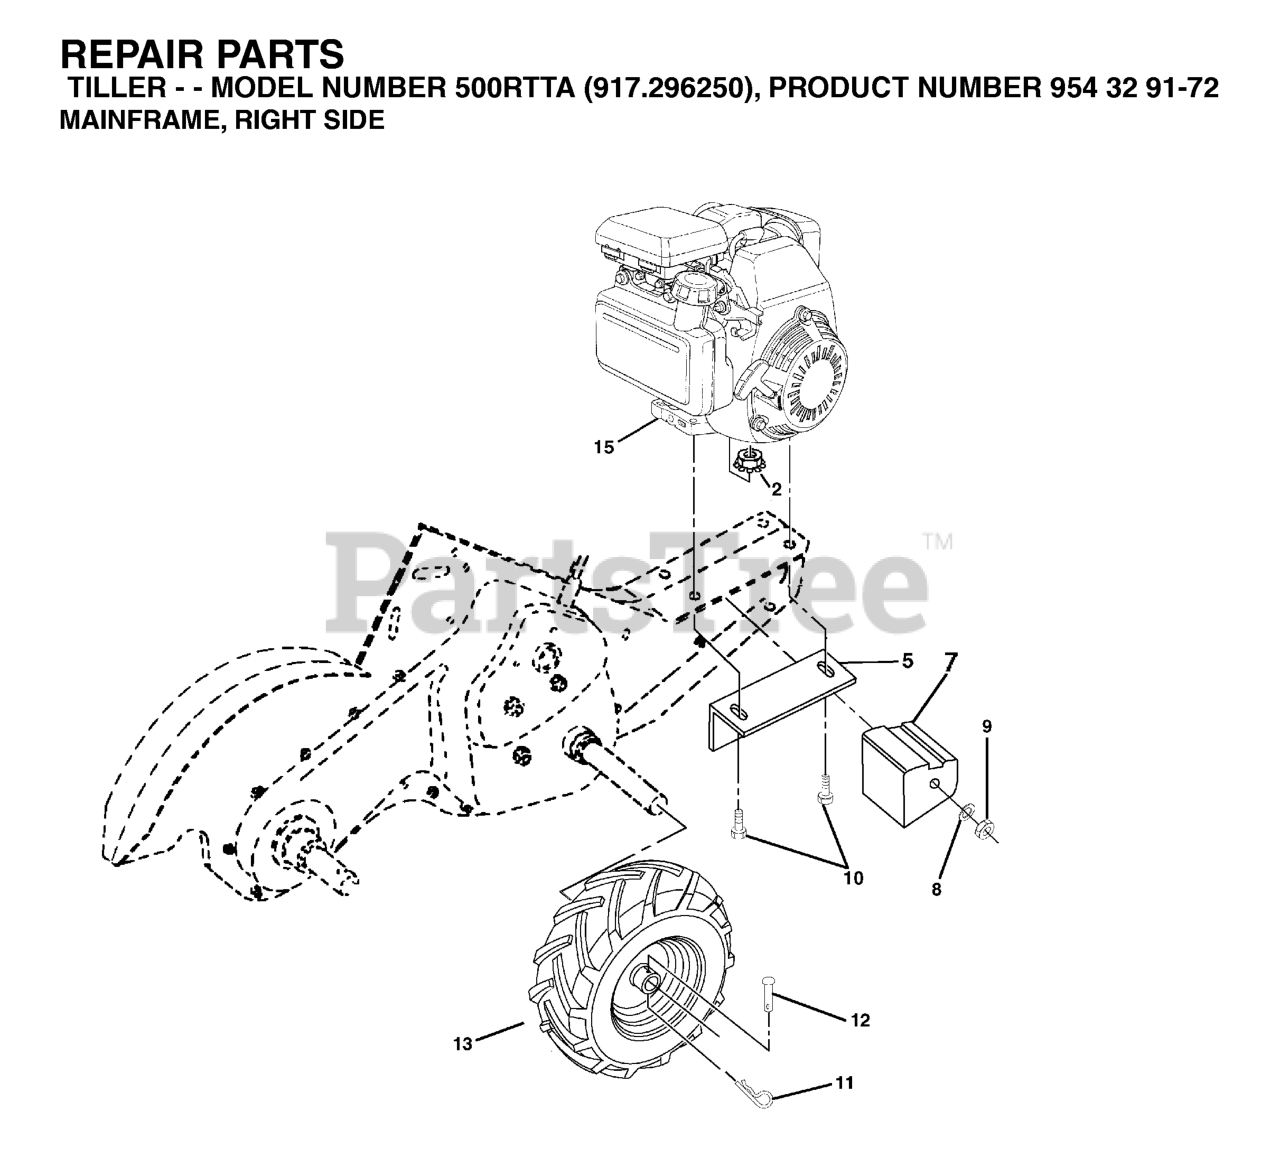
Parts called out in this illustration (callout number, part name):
2	LOCKNUT-FLANGE 5/16-18
5	DNO BRACKET RH CRT
7	COUNTERWEIGHT, RH
8	WASHER, LOCK 3/8
9	NUT.HEX.3/8-16UNC
10	BOLT
11	RETAINER M
12	RIVET,DRILLED
13	TIRE.13X5-6.CHEVRON.TILLER
